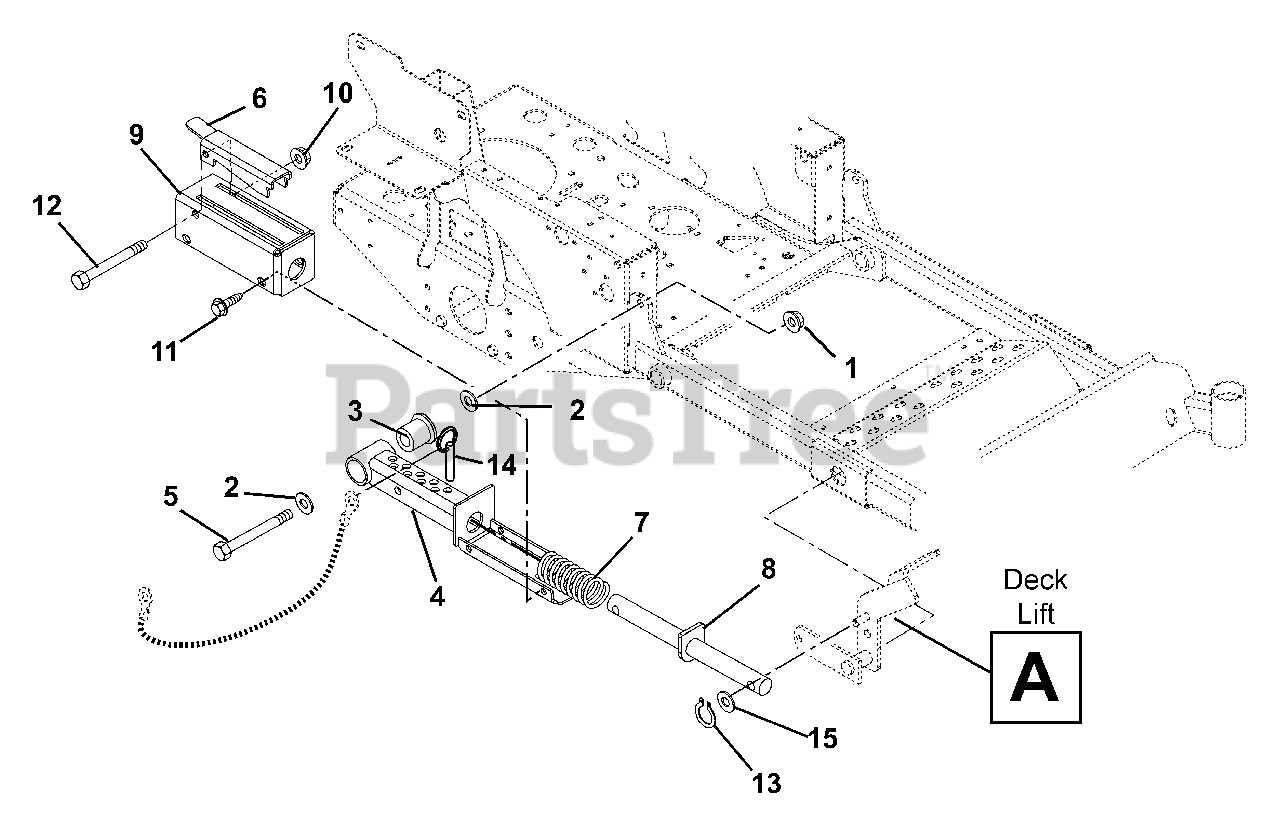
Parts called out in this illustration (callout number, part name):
1	Nut, Locking Top Flange .50-13
2	Washer, Flat Steel .531 x 1.25 x .10
3	Bearing, Pedestal
4	Weldment, Mechanical Lift
5	Bolt, Hex .50-13 x 3.75 Grade 5
6	Lock-Up, Mechanical Lift
7	Spring, Compression 1.13 x 1.48 x 5.10
7	Spring, Compression 1.13 x 1.47 x 5.10
8	Weldment, Mechanical Lift Shaft
9	Weldment, Mechanical Lift Cover
10	Nut, Nyloc Flange 3/8-16
11	Screw, Tapping .38-16 x .50 Hex Washer Head
12	Bolt, Hex .38-16 x 3.25 Grade 5
13	Ring, Retaining External .50 x .05
14	Pin, Spring Ball .375 O.D. x 1.50
15	Washer, Flat Steel .656 x 1.31 x .095
